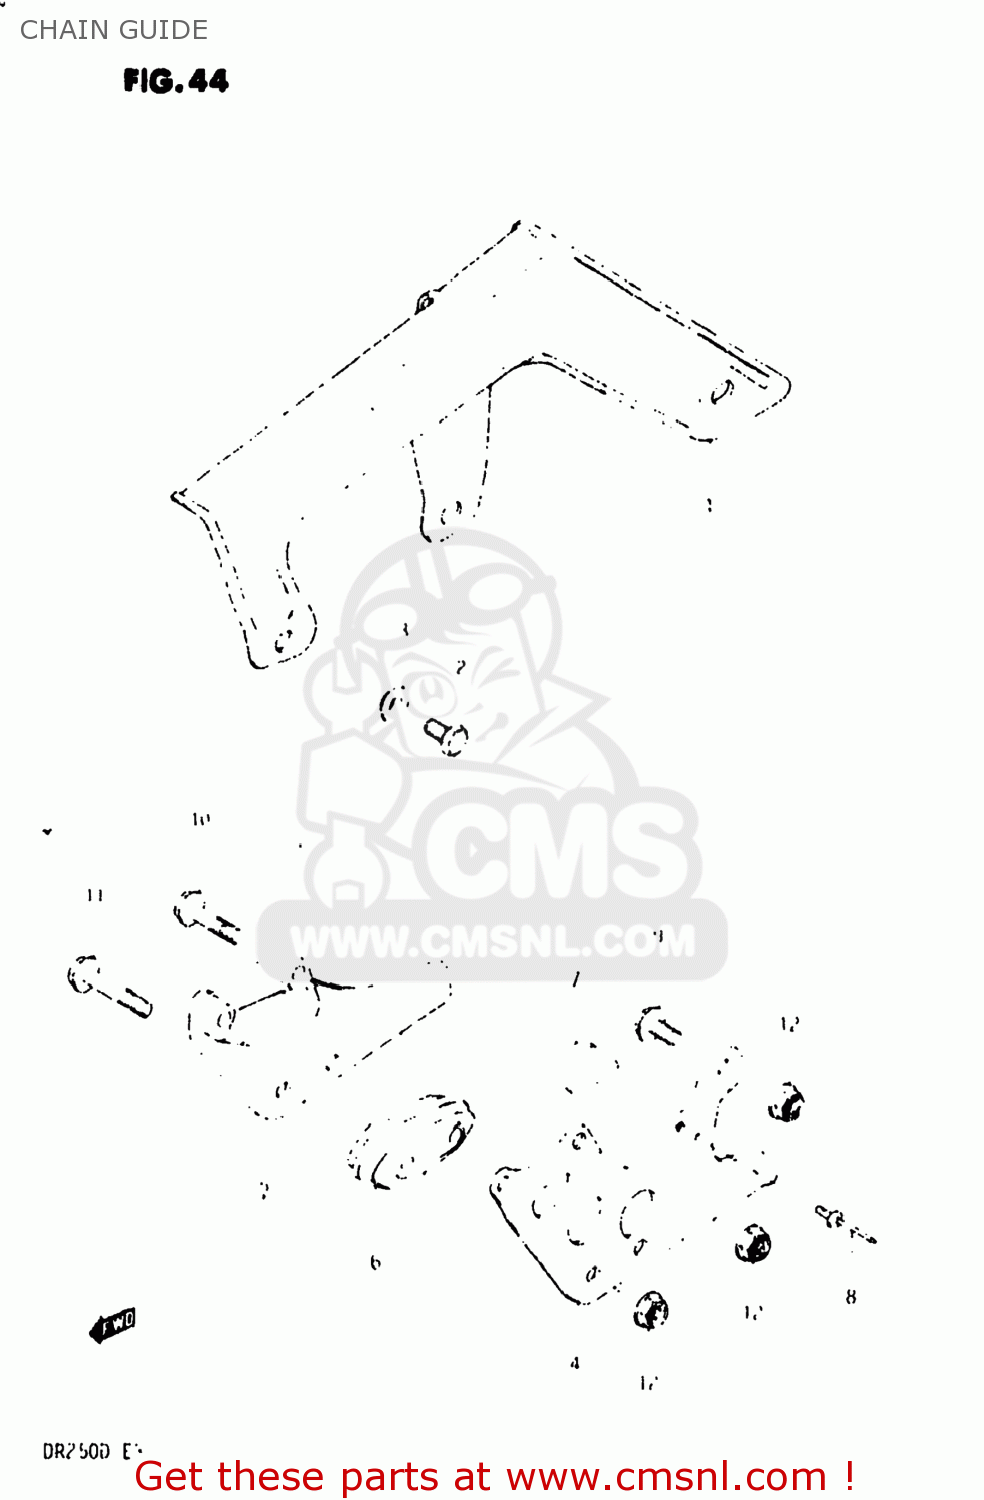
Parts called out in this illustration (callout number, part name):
1	CASE,CHAIN
2	BOLT
3	WASHER,LOCK
5	PLATE,CHAIN GUIDE,INNER
6	DEFENSE,CHAIN GUIDE
7	PAD,DRIVE CHAIN GUIDE
8	RIVET
9	BOLT
10	BOLT 6X35
11	BOLT
12	NUT
